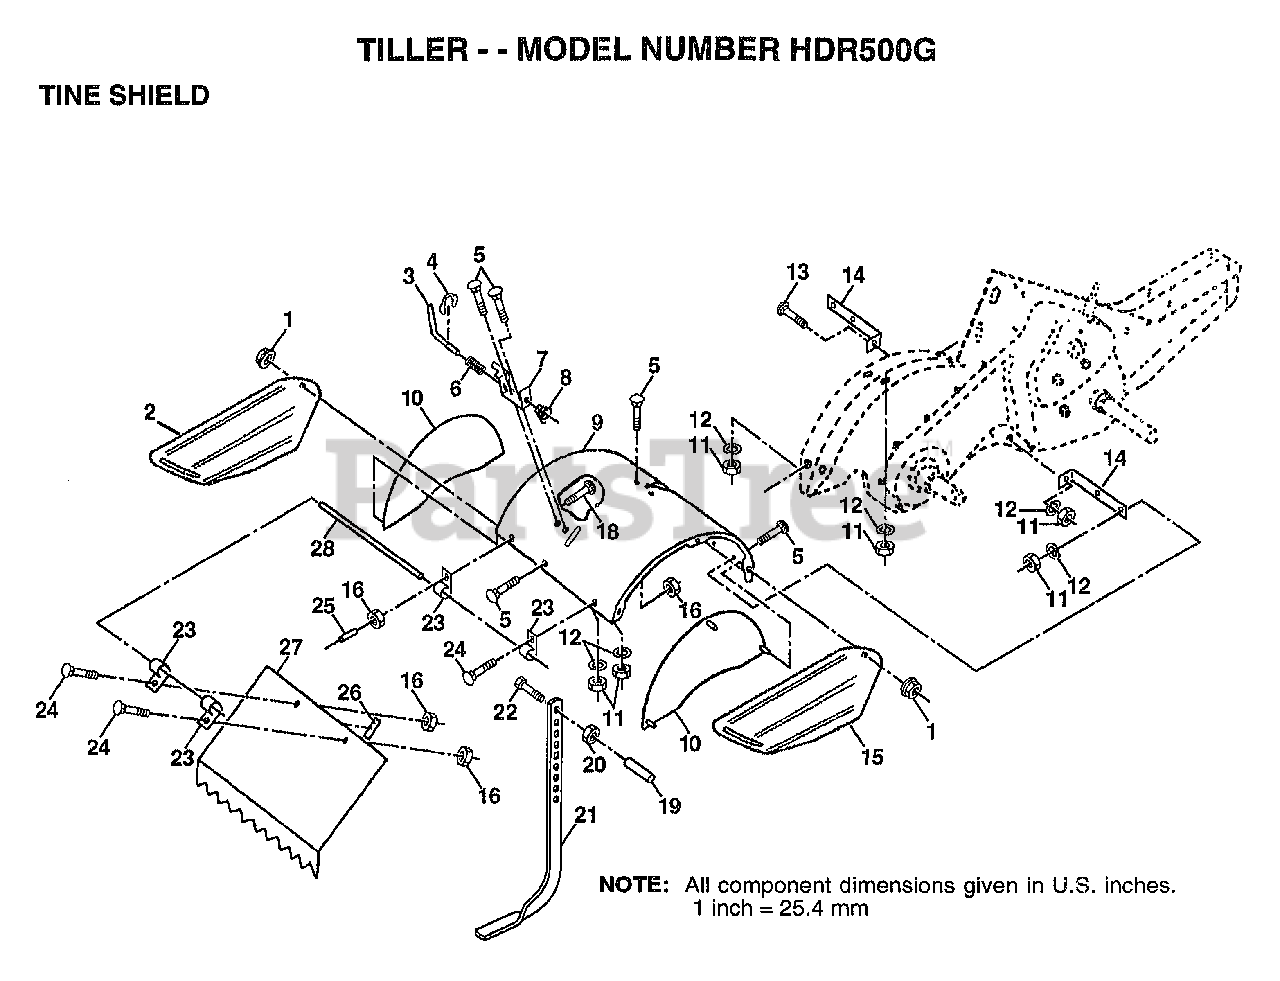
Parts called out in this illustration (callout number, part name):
1	NUT
2	SHLD.SIDE.OUTER.L
3	STAKE PIN TI
4	KLIP RING TI
5	BOLT
6	SPRING TI
7	LATCH BRACKET TI
8	SPRING CRT
9	SHIELD TINE
10	SHIELD SIDE
11	NUT.HEX.5/16-18
12	LOCKWASHER
13	BOLT
14	BRKT SHIELD TINE
15	SHLD.SIDE.OUTER.R
16	NUT
18	BOLT
19	GRIP CRT
20	NUT.HEX.3/8-16UNC
22	BOLT
23	HINGE CRT
24	BOLT
25	VINYL CAP TI
26	PAD IDLER TI
27	"SHIELD,LEVEL"
28	PIN HINGE
